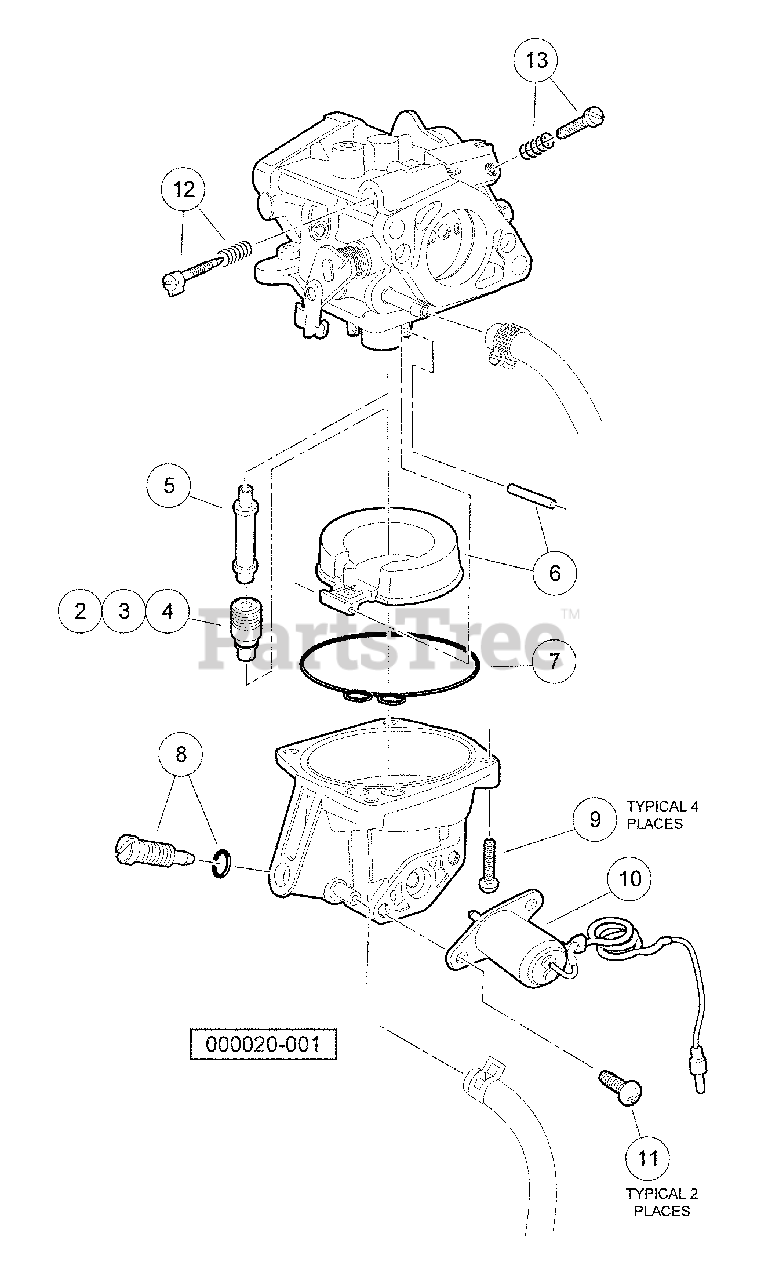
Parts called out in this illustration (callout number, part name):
1	Carburetor, Seal Shaft
2	Jet, GX620, #102 (8000 ft. and higher (2438 m and higher))
3	Jet, GX620, #105 (5000-8000 ft. (1524-2438 m))
4	Jet, GX620, #108 (0-5000 ft. (0-1524 m))
5	Nozzle, Main
7	Gasket Set
8	Screw Set, Drain
9	Screw-Washer, M4 X 14
10	Valve Assy., Solenoid
11	Screw-Washer, M5 X 12
12	Screw Set, Left
13	Screw Set, Right
